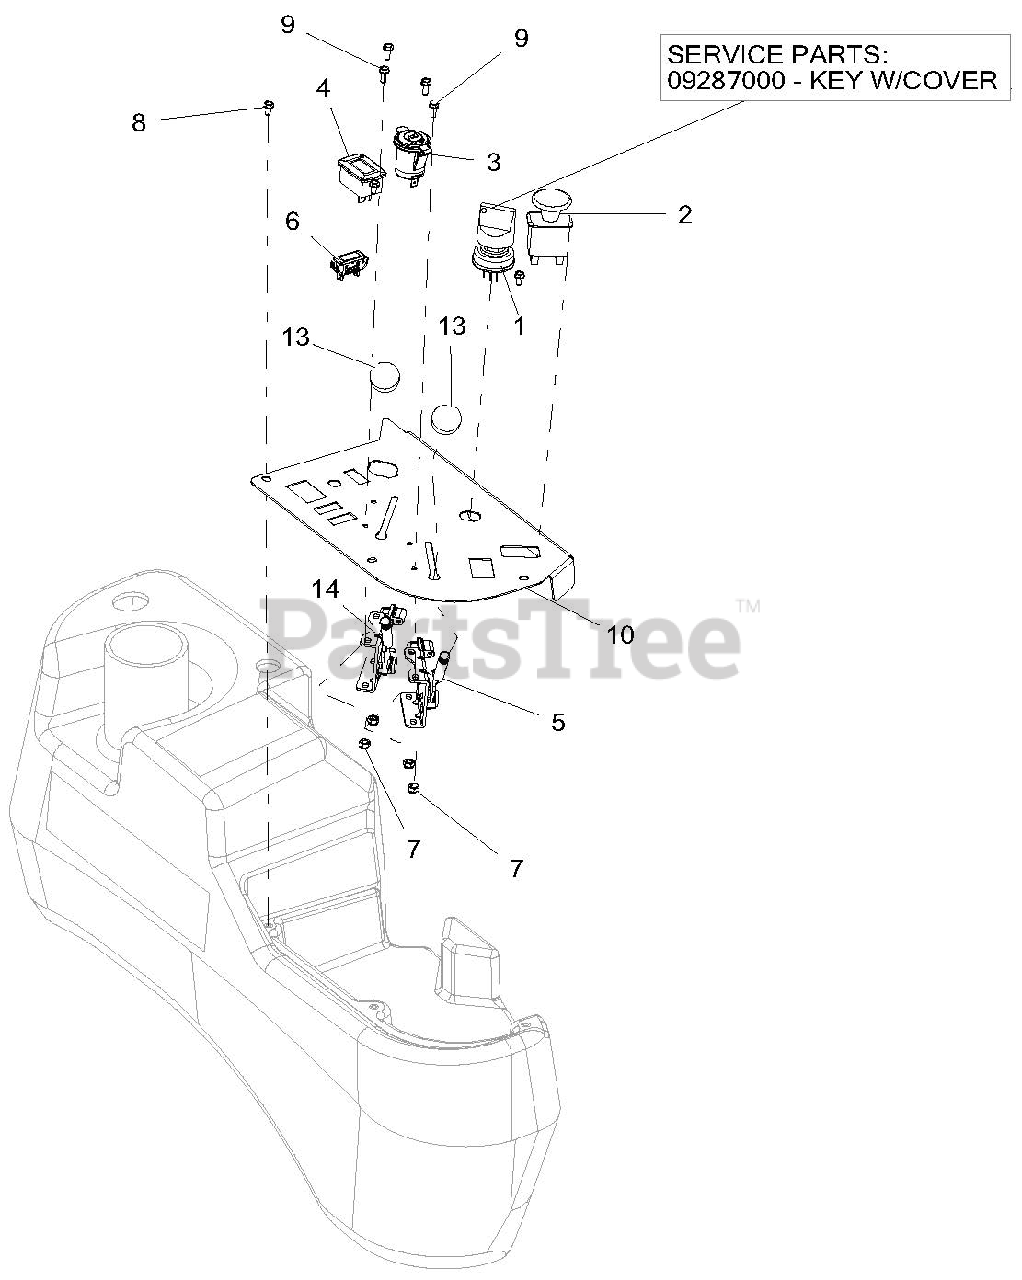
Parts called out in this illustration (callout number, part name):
1	SWITCH, IGNITION
1	KEY W/COVER
2	SWITCH, CLUTCH
3	PORT, 12 VOLT POWER
4	METER, HOUR W/MAINTENANCE
5	CABLE, PRO-CONTROL THROTTLE
6	LIGHT, INDICATOR
7	NUT-LK-NYL #10-24 YWZC
8	SCR-MCH 10-24X.38 HWHSTAINLESS
9	@SCR-MCH 10-24X.50 HWH YWZC
10	PANEL, CONTROL
13	KNOB, CONTROL BLACK .38-16X.50
14	CABLE, PRO-CONTROL THROTTLE
